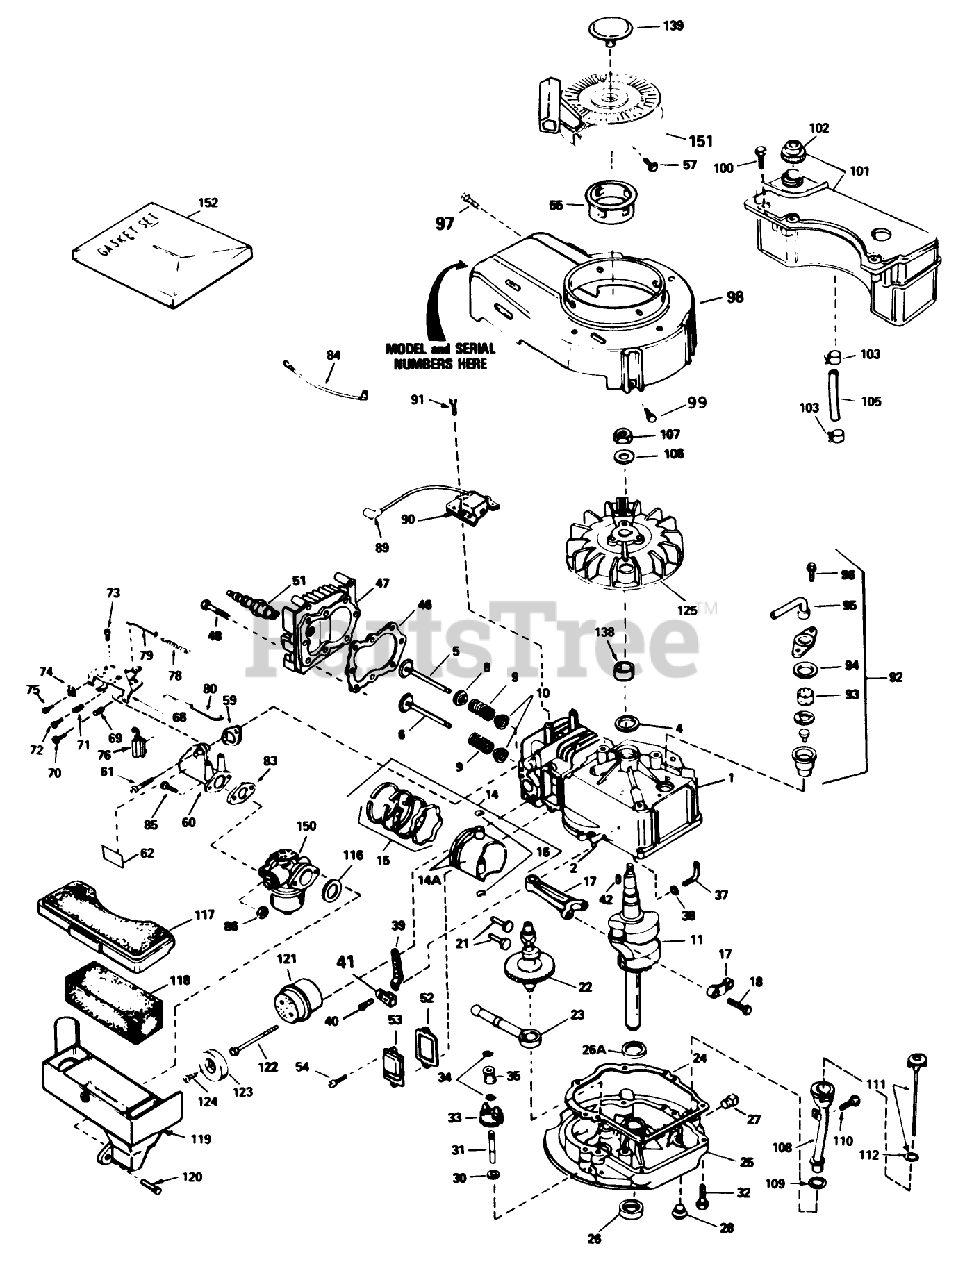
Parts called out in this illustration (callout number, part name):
1	Cylinder Assy. (Incl. #24)
2	Pin-Dowel
4	Seal-Oil
5	Valve, Intake (Std.) (Incl. Ref. #40)
5	Valve, Intake (1/32" oversize)(Incl. No. 40)
6	Valve, Exhaust (Std.)(Incl. No. 40)
6	Valve, Intake (1/32" oversize)(Incl. No. 40)
8	Seal Assy., Intake
9	Spring-Valve
10	Cap-Valve, Spring
11	Crankshaft
14	Piston, Pin Ring Assy. (Std.) (Incl. Ref. #13A, 14 15)
14	Piston, Pin Ring Assy. (.010 oversize) (Incl. Ref. #13A, 14 15)
14	Piston, Pin Ring Assy. (.020 oversize) (Incl. Ref. #13A, 14 15)
14A	Piston Pin Assy. (Incl . Ref. . #14) (Std.)
14A	Piston Pin Assy. (Incl. Ref. #14) (.010 Oversize)
14A	Piston Pin Assy. (.020 oversize) (Incl. Ref. #14)
15	Ring Set (Std.)
15	Ring Set (.020" OS)
15	Ring Set (.010" OS)
16	Ring-Retaining, Piston Pin
17	Rod Assy., Connecting (Incl. Ref. #17)
18	Bolt-Rod, Connecting
21	Lifter-Valve
22	Camshaft(Mech.Comp. Release)
23	Oil Pump ASM
24	Gasket
25	Flange-Mounting (Incl. Ref. #26, 27 39)
26	Seal-Oil
26A	Washer-Thrust
27	Plug-Pipe
28	Plug Oil Drain
30	Washer-Flat
31	Shaft-Governor
32	Screw (1/4-20 x 1-1/4)
33	Governor Gear ASM
34	Ring-Retaining
35	Spool-Governor
37	Rod, Governor (Incl. No. 36)
38	Washer-Flat
39	Governor Lever
40	Screw
41	Clamp-Lever, Governor
42	Key-Flywheel
46	63573 GIL 42 SNWTHW
47	Head-Cylinder
48	Screw (5/16-18x1-1/2)
51	Spark Plug-Resistor (R J19 L M)
52	Gasket-Breather
53	Cover-Valve
54	Screw
55	Hub-Starter
57	Screw, Hex Hd.
59	Gasket-Intake
60	Pipe-Intake (Incl. Ref. #59)
61	Screw (1/4-20 x 1)
62	Decal-Primer
68	Control Assy.-Remote Speed (Incl. Ref. #69 thru 72 76)
69	61709/GIL1515A/95-5
70	Screw
71	Spring-Compression
72	Screw
73	Screw (10-24 x 9/16)
74	Conduit
75	Screw (10-32 x 3/8)
76	Terminal
78	Spring Governor
79	2035A67 ADD.ASSEMBL
80	Link-Throttle
83	Gasket
84	Wire-Ground
86	Nut and Lock Washer (1/4-28)
89	Cover-Spark Plug
90	Solid State
91	Screw
92	Breather Assy. (Incl. Ref. #46 thru 51)
93	Element-Breather
94	Gasket-Breather
95	Tube, Breaker
96	Screw (10-24 x 9/16)
97	Screw (10-24 x 9/16)
98	Housing-Blower
99	Screw (1/4-20 x 1/2)
100	Screw (10-32 x 35/64)
101	Tank Assembly-Fuel (Incl. Ref. #102)
102	Cap-Fuel
103	Clamp-Line, Fuel
105	Line-Fuel
106	Washer-Belleville
107	Nut-Flywheel
108	Tube-Oil Fill
109	Gasket
110	Screw (10-32 x 1/2)
111	Dipstick-Oil (Incl. Ref. #112)
112	O-Ring
116	Gasket-Cleaner, Air
117	Cover-Air Cleaner
118	Filter-Air Cleaner
119	Body Air cleaner
120	Screw
121	Muffler (Incl. Ref. #122)
122	Screw
123	Cover-Muffler
124	Screw (8-32 x 3/8)
125	Flywheel
138	Spacer
139	Plug Starter
150	Carburetor (Incl. Ref. #83)
151	Starter-Rewind
152	Gasket Set
